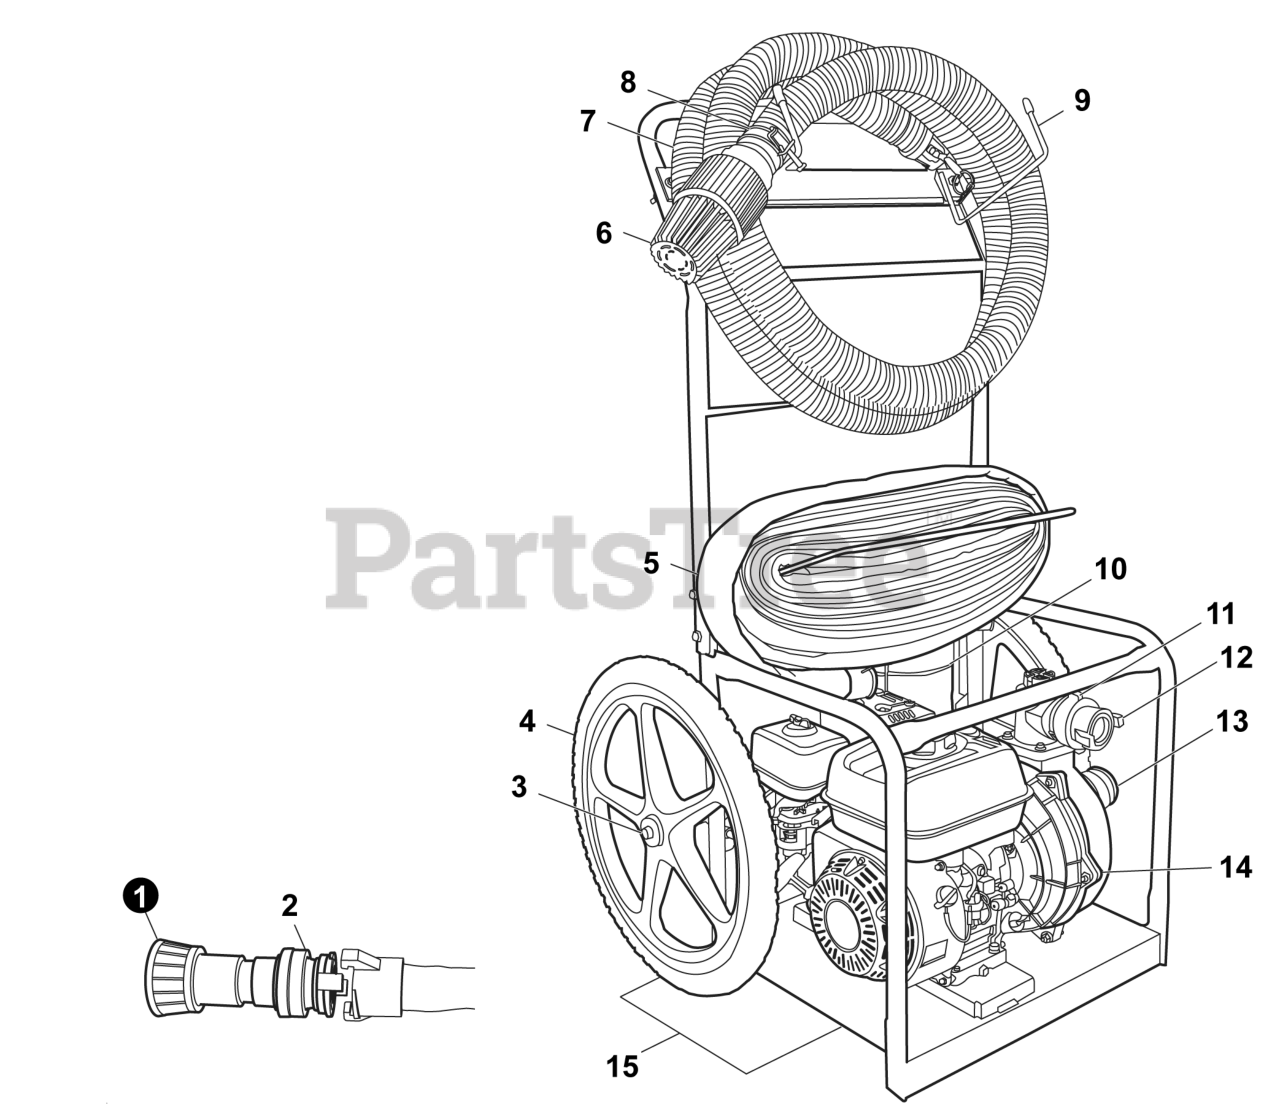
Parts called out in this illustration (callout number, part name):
1	NOZZLE, FIRE
2	ADAPTOR, FIRE HOSE 1.5"" MNPT
3	AXEL W/HARDWARE
5	HOSE, FIRE
6	VALVE, 2"" FOOT
7	HOSE, SUCTION
9	HANGER, SUCTION HOSE
10	HOLDER, PRIMING JUG
11	ADAPTOR, REDUCING, 2"" X 1.5""
12	ADAPTOR, FIRE HOSE 1.5"" FNPSH
13	ADAPTOR, 2"" FEMALE NPT
14	ASSY., WATER PUMP
15	FRAME W/ WHEELS
